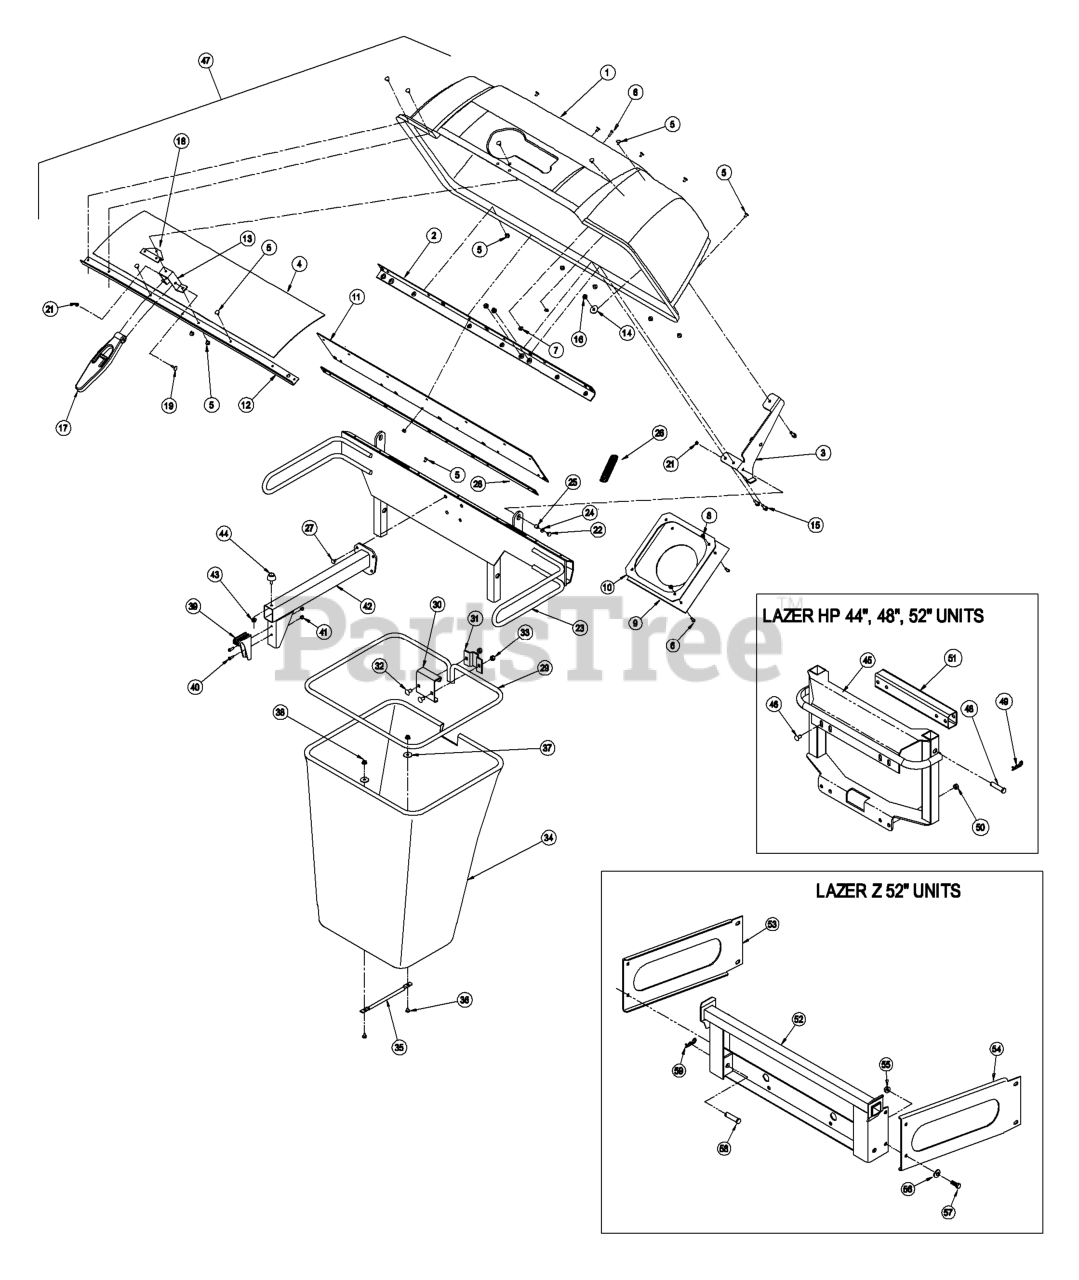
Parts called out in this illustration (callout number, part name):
2	STIFFENER-BAGGER, TOP
3	HINGE ASM
4	SCREEN-BAGGER
5	RIVET-BLIND
6	SCREW-HEAD, TRUSS
7	WASHER-FLAT
8	NUT-LOCK, NI
9	SEAL-CHUTE
10	CLAMP-SEAL
11	SEAL
12	SUPPORT-SCREEN
13	ANCHOR-LATCH
15	SCREW-HH
18	REINFORCEMENT-LATCH
19	SCREW-HH
21	NUT-LOCK, NI
22	SCREW-HH
24	WASHER-FLAT
26	SPRING-EXTENSION
27	SCREW-HH
28	PLATE-BACKING
29	FRAME-BAG
30	HANGER-BAG
32	BOLT-CARR
33	NUT-LOCK, NI
35	HANDLE-BAG
36	BOLT-CARR
38	NUT-LOCK, NI
40	SCREW-PPH
45	BAGGER MOUNT ASM
46	SCREW-HH
47	ASM, HOOD
48	PIN-CLEVIS
49	PIN-COTTER
50	NUT-HF
51	TUBE,SPACER
52	MOUNT-BAGGER
54	BRACKET-FRAME, RH
55	NUT-HHF, WHIZ
56	WASHER-BELLEVILLE
57	SCREW-HH
58	PIN-CLEVIS
